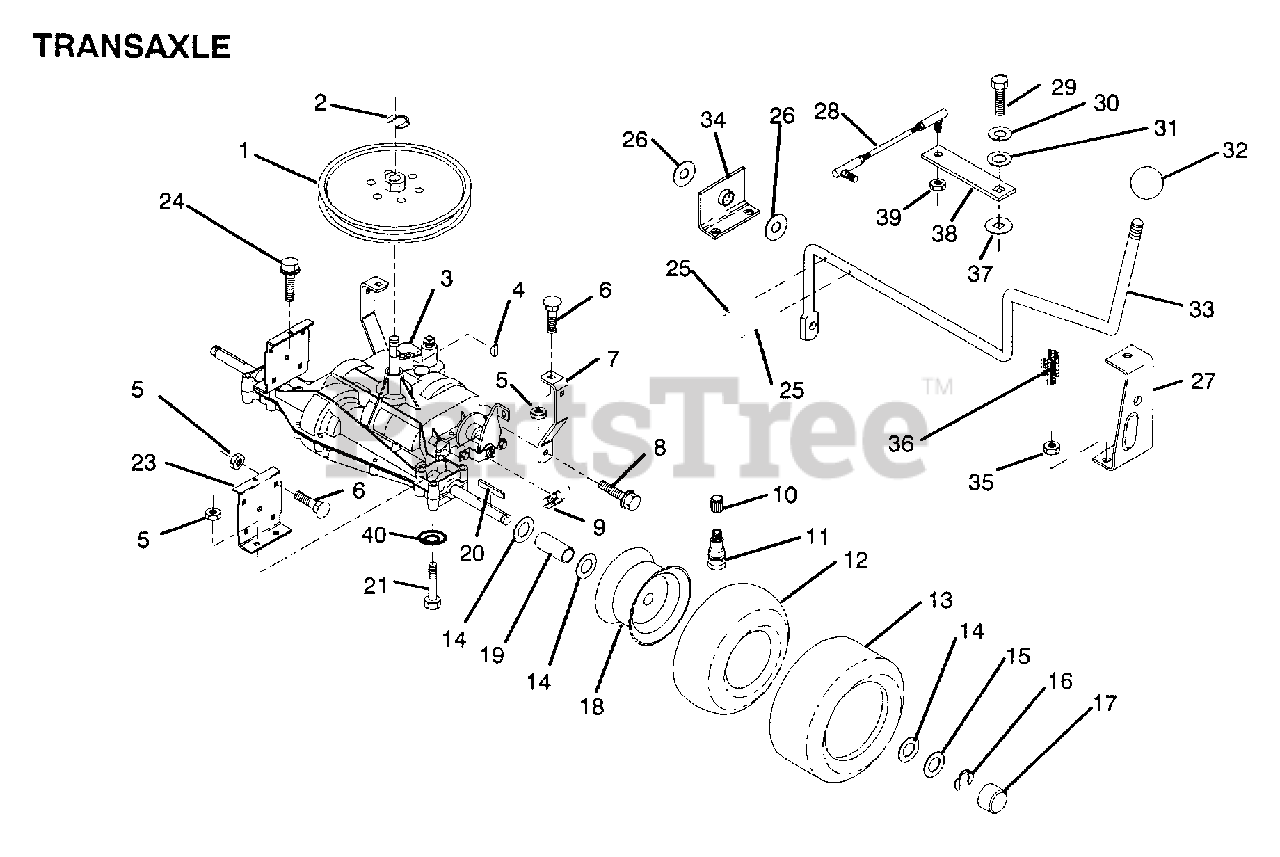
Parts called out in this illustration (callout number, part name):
1	PULLEY
6	BOLT
7	"STRAP,TORQUE"
8	SCREW LT
10	VALVE CAP
11	VALVE STEM LT
12	TUBE.16X6.5/7.5-8
14	WASHER
15	WASHER
16	E-RING LT
17	HUB CAP
19	SPACER
20	SQUARE KEY
21	BOLT
23	"BRKT,TRANSAXLE"
24	SCREW
25	PIN COTTER 1/8
28	LINK SHIFT
30	LOCKWASHER
31	WASHER LT
32	KNOB T (1/2-HOLE)
34	"SUPT,HDLE SHT LH"
36	EXT SPRING
37	WASH-SHFT PLT LT
39	NUT.LOCK.5/16-24
40	WASHER
